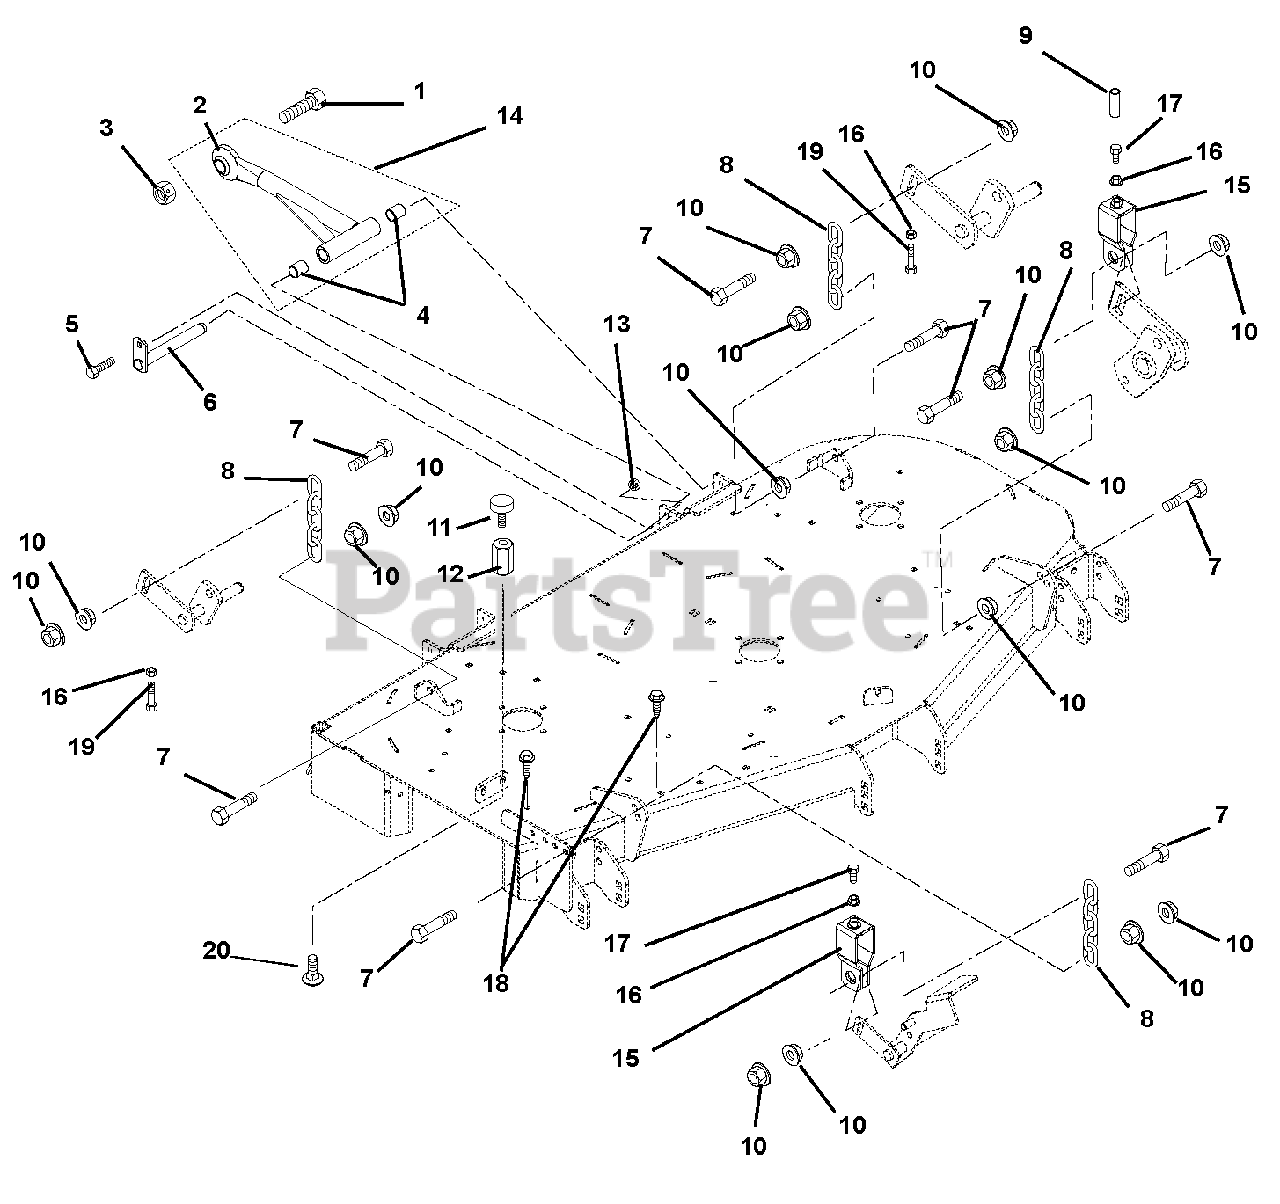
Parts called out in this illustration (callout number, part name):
1	Bolt, Hex .875-9 x 2.75 Grade 5
2	Mower Mounting Arm Weldment
3	Nut, Locking-Center .875-9
4	Bearing, .75 x .875 x 1.00
5	Bolt, Hex .38-16 x .75 Grade 5
6	Weldment, Mower Mounting Pin
7	Bolt, Hex M12-1.75 x 50 Grade 5
8	Chain, Link
9	Cap, Vinyl .50ID x 1.50LG x .055
10	Nut, Spin Lock-Flange M12-1.75
11	Bumper, Rubber
12	Coupling Nut, .31-18 x 3.00
13	Nut, .38-16 Nyloc Flange
14	Assembly, Mower Mounting Arm (Includes item # 2 and item # 4)
15	Bracket, Deck Leveling
16	Nut-Jam .312-18
17	Bolt, Hex .31-18 x 2.00 Full Thread
18	Screw, Tapping .38-16 x .50 Hex Washer Head Thread (992156)
19	Bolt, Hex .312-18 x 1.50 Grade 5
20	Bolt, Round Head Square Neck .31-18 x .75 Loc-Tite
